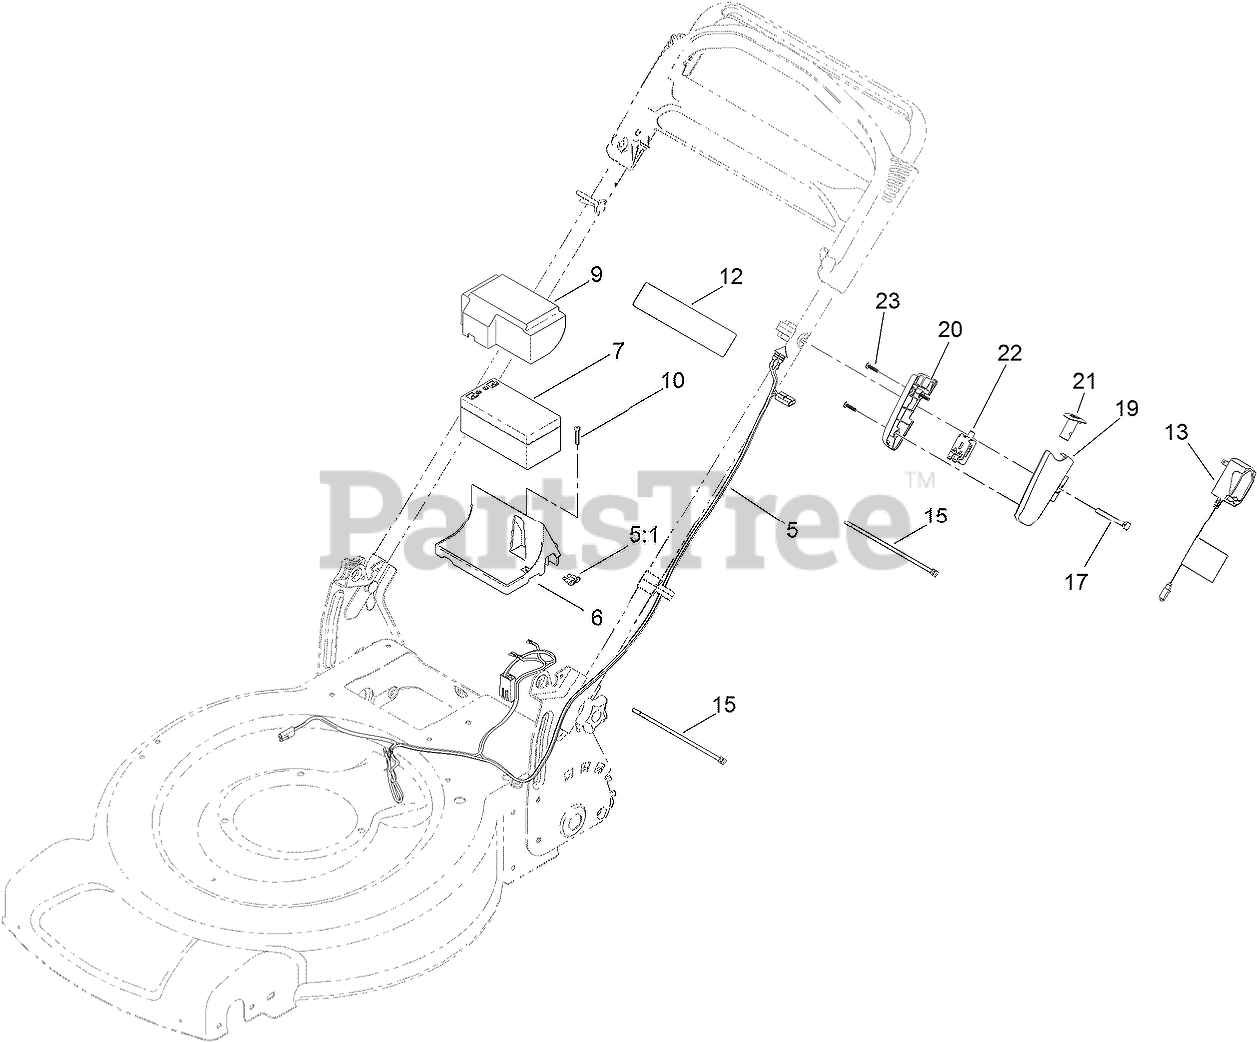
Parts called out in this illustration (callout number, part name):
5	HARNESS-WIRE
5:1	FUSE-40 AMP
6	TRAY-BATTERY
7	BATTERY-WET
9	COVER-BATTERY
10	SCREW-PPH, PLASTITE
12	DECAL-WARNING
13	CHARGER-BATTERY
15	TIE-CABLE
17	SCREW-HH
19	HOUSING-SWITCH, LH
20	HOUSING-SWITCH, RH
21	BUTTON-SWITCH
22	SWITCH-PUSH BUTTON
23	SCREW-PPH
